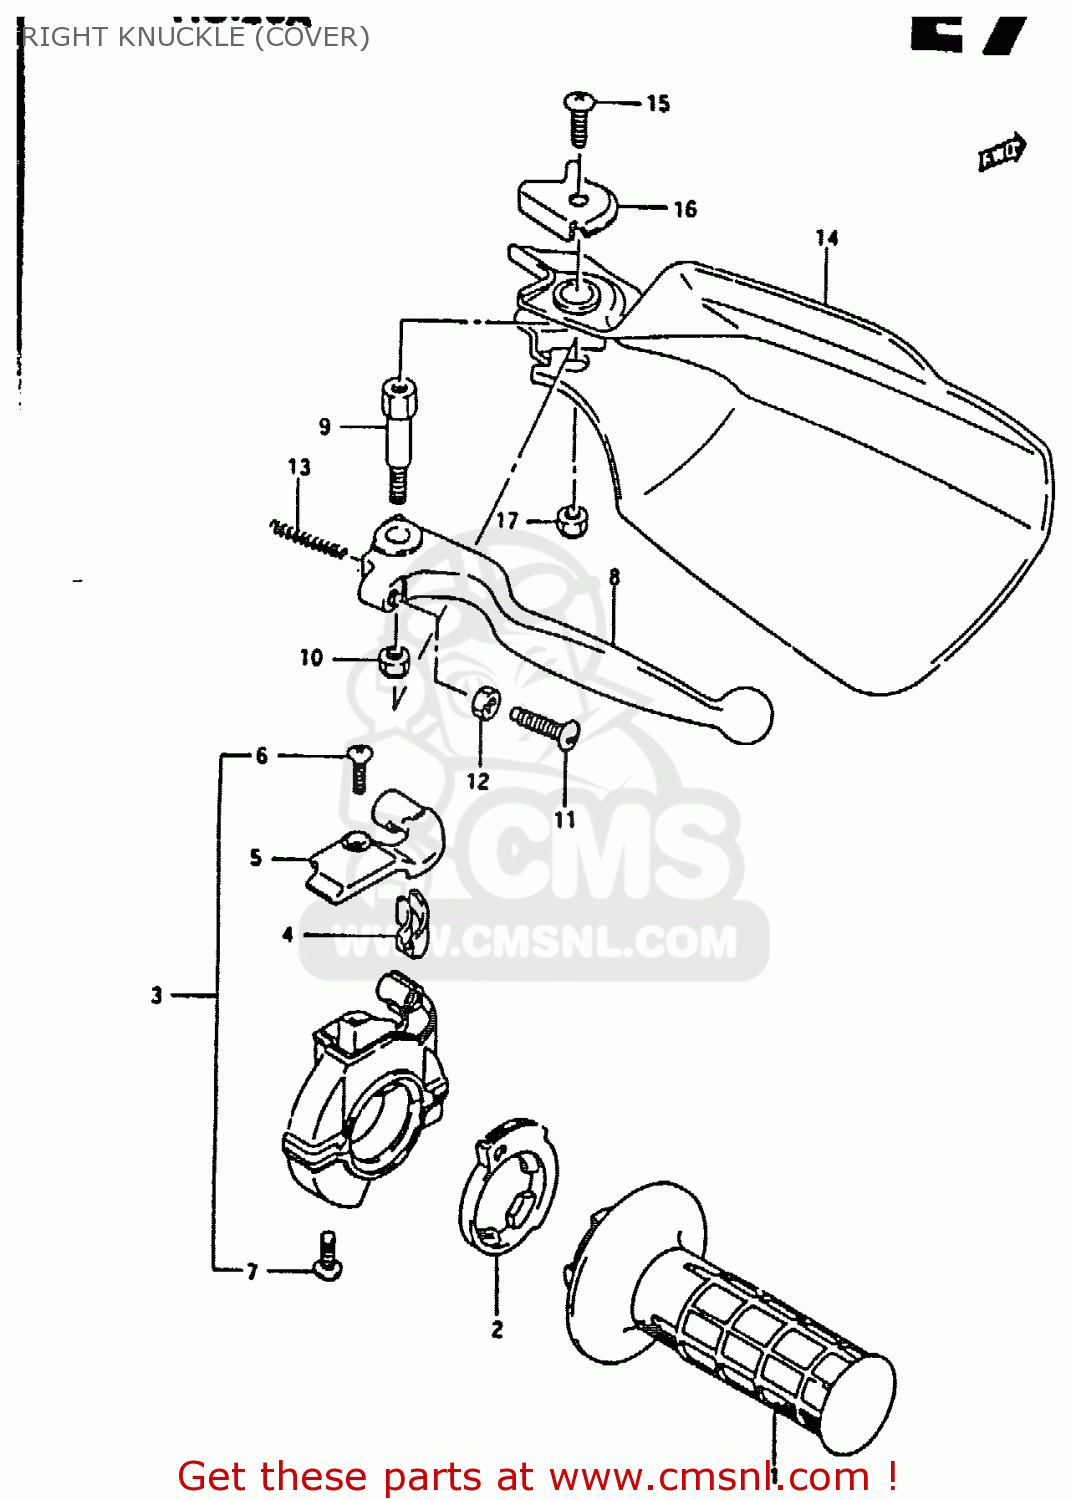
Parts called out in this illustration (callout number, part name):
1	GRIP,THROTTLE
2	ROTOR,THROTTLE GRIP
3	CASE ASSY,THROTTLE
4	GUIDE PIECE,THROTTLE
5	COVER,THROTTLE CASE
6	SCREW,UPPER
7	SCREW
8	LEVER,BRAKE
9	BOLT,BRAKE LEVER PIVOT
10	NUT 6MM
11	BOLT,ADJUST
12	NUT ,5MM
13	SPRING,RETURN
14	COVER,KNUCKLE,R
15	SCREW
16	PLATE,KNUCKLE COVER,R UPR
17	NUT 6MM
